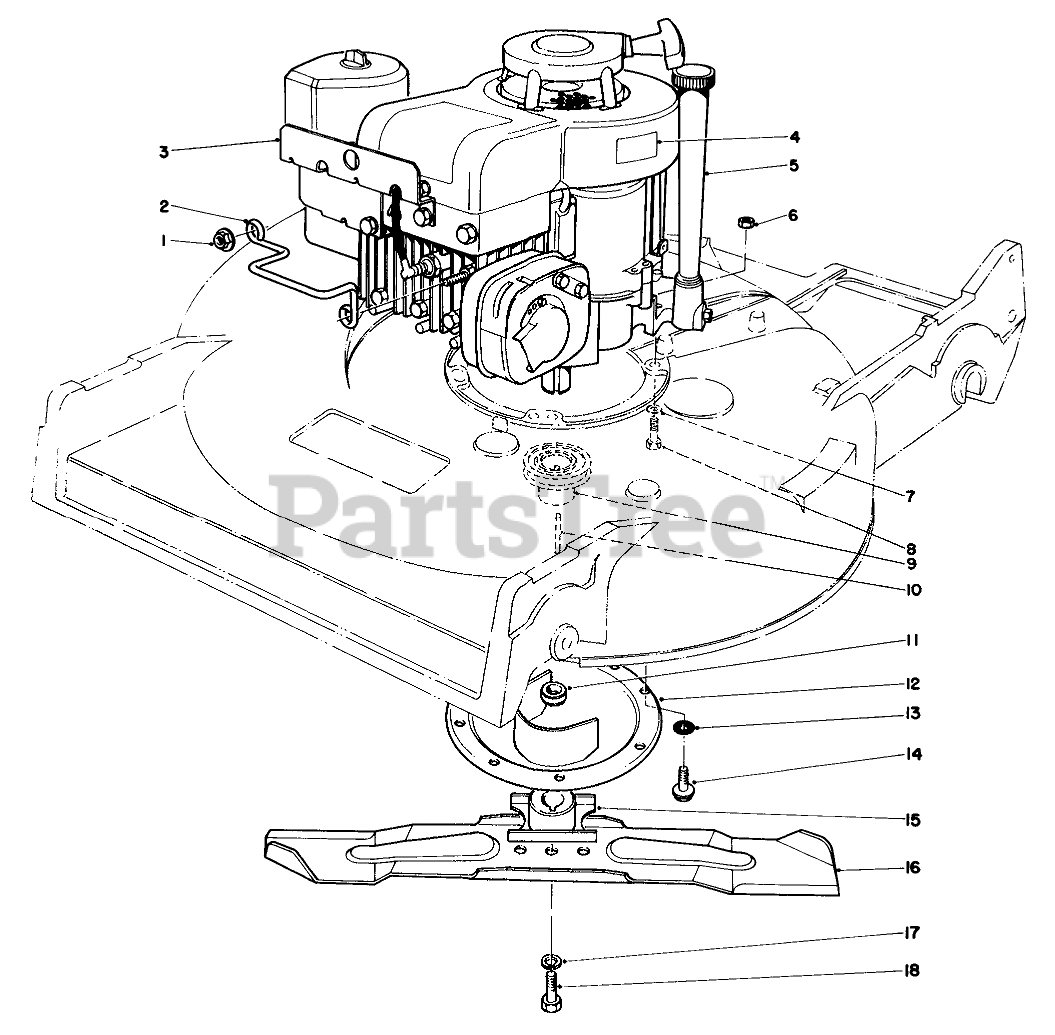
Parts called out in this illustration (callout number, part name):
1	NUT-HF
2	Protector-Spark Plug
3	ENGINE GD BRKT
4	Decal-Oil Caution
5	Engine
6	NUT-LOCK, CONE
7	WASHER-PLAIN
8	SCREW-HH
9	PULLEY DRIVER
10	KEY-SQUARE
11	BLADE RETAINER SPACER
12	Crankshaft Protector Assy.
13	WASHER-LOCK, INTERNAL
14	SCREW-HWHTF
15	BLADE RETAINER W A
16	BLADE-21in
17	WASHER-LOCK
18	BLADE SCREW
